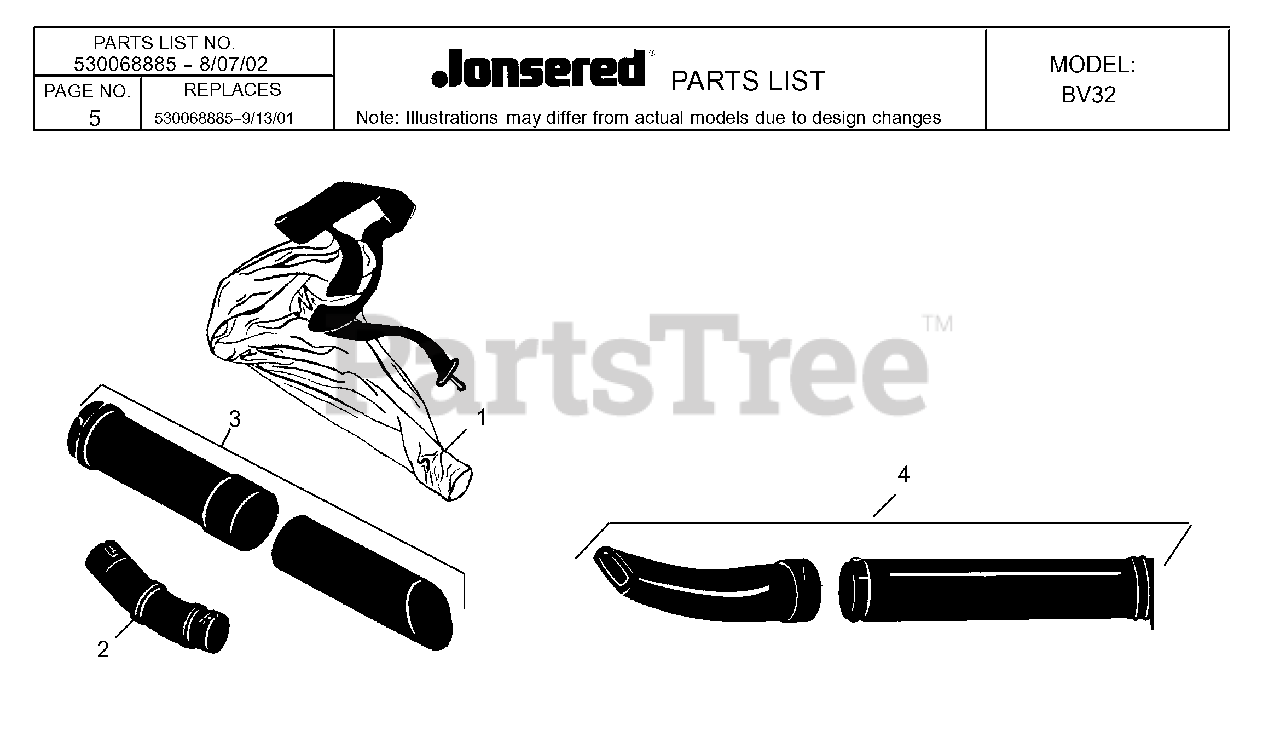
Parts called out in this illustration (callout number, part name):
1	COLLECTION BAG W/ STRAP
2	ELBOW TUBE
3	VAC TUBE SET
4	TUBE & NOZZLE ASS'Y
